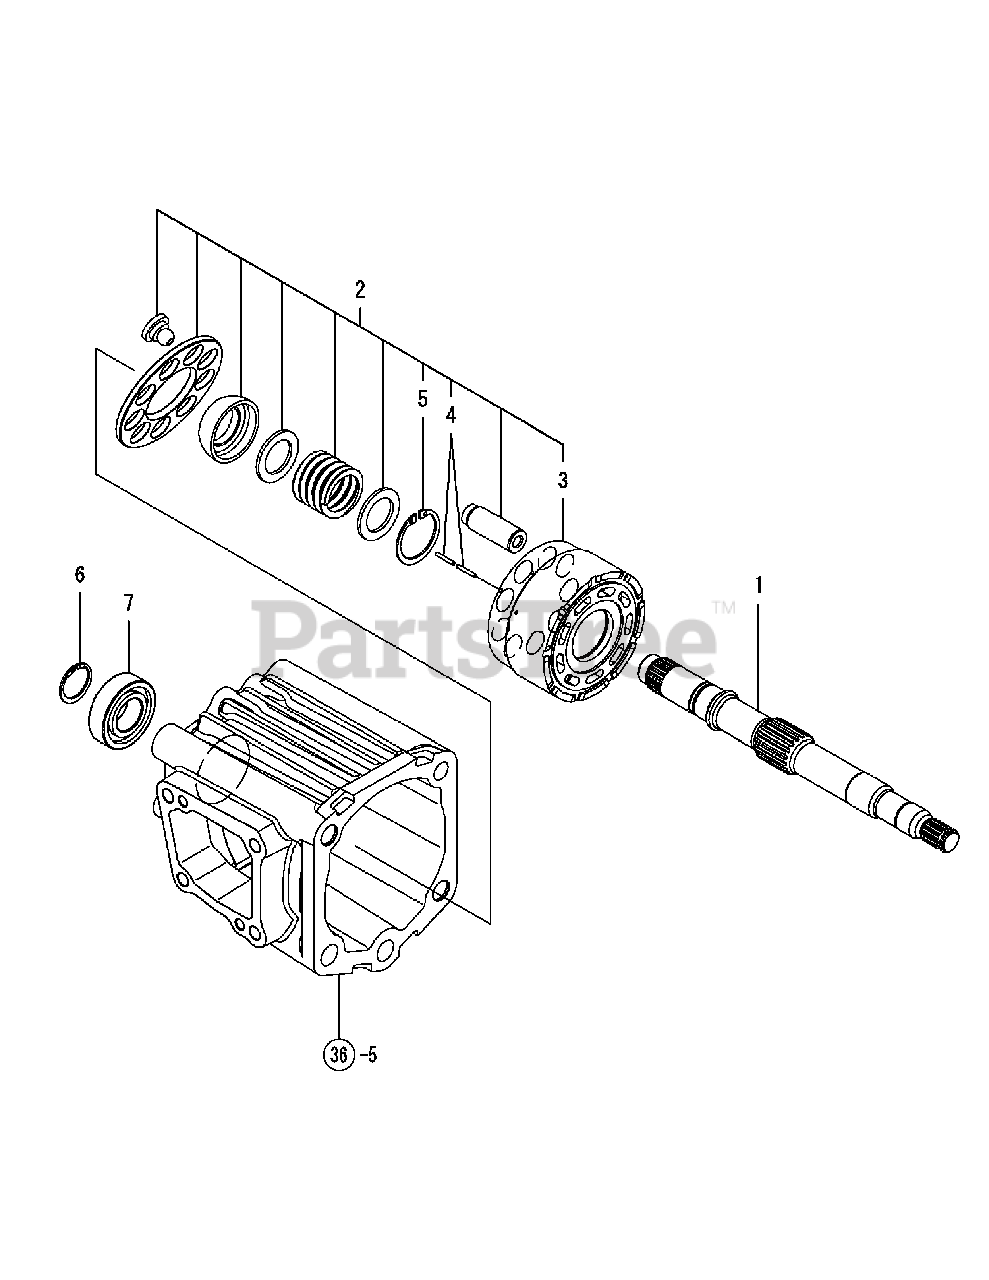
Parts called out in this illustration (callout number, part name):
1	MOTOR SHAFT (K93)
2	BLOCK ASSY, CYL
3	BLOCK, CYLINDER
